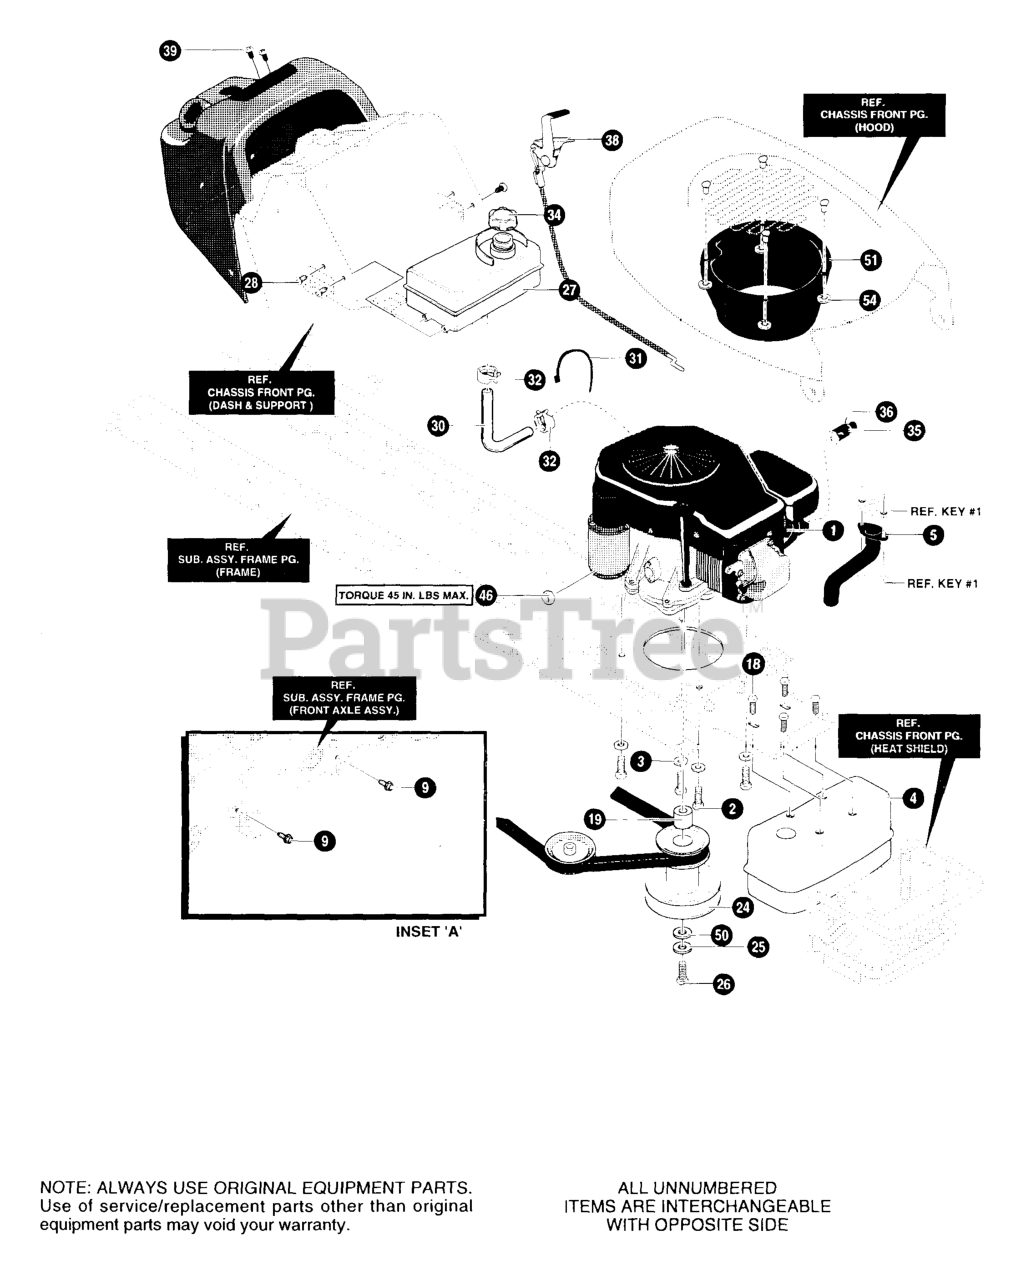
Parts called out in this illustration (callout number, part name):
1	ENGINE 16HP INTEK
2	SCREW, M8-1.25X25MM
3	WASHER, EXLK.384X.69X.04
4	MUFFLER, SINGLE-CYLINDER
5	EXHAUST TUBE
9	SCREW, 5/16-18 x 0.75 HHWATAP
18	SCREW, 1/4-20X.63 HHWATAP
19	SPACER, SLEEVE
24	PULLEY, STACK ASSY
25	WASHER, REGSPTLK.459X.78X.12
26	SCREW, 7/16-20NF-1.50
27	TANK, Fuel 1.4 Gal.
28	SCREW, 15TPIX PANHTAP
30	TUBING,.25X.50
31	CABLE TIE
32	CLAMP, HOSE SCREW TYPE
34	CAP, FUEL
35	OIL DRAIN VALVE ASSEMBLY
36	CAP, OIL DRAIN VALVE ASSY
38	THROTTLE CONTROL
39	SCREW, #8-16X.50 TRCRTAP
46	NUT 1/4-20 REGHXJAM
50	FLATWASHER .480X1.00X.25
51	PLENUM
54	PUSHNUT
